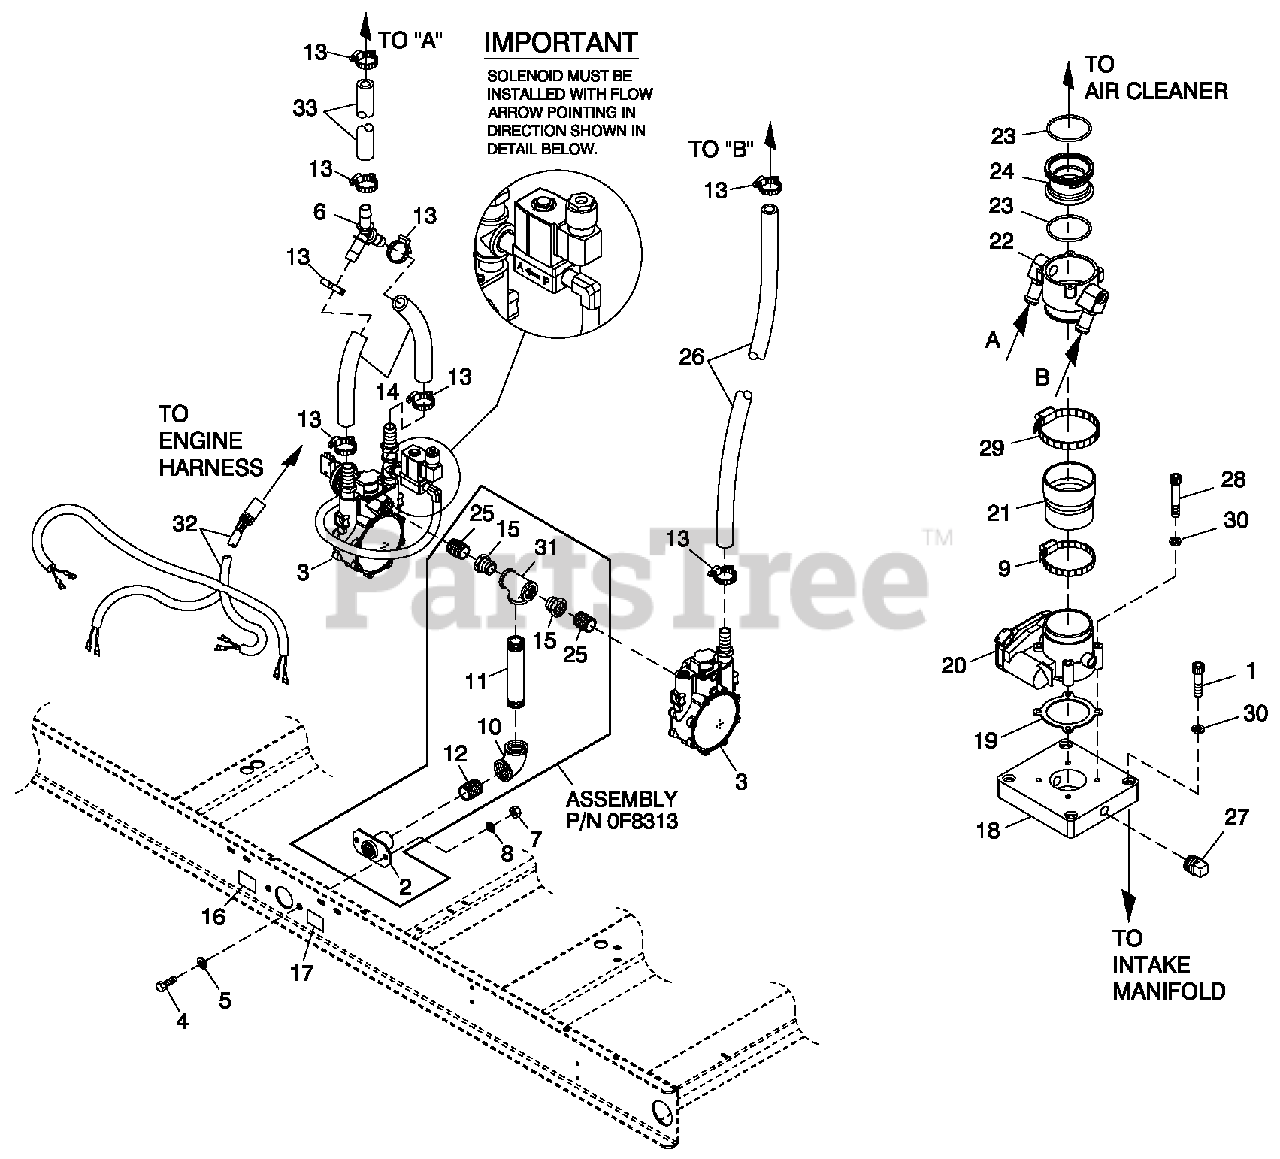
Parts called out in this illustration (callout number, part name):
1	SCREW SHC M6-1.0 X 25 G12.9 ZP
2	SUPPORT NAT GAS SOLENOID
3	REG ASSY 4.6L 80KW NG CPL
4	SCREW HHC M12-1.75 X 20 G8.8
5	WASHER FLAT 1/2 ZINC
6	Y CONNECTOR 500 SERIES BARBS
7	NUT HEX M12-1.75 G8 YEL CHR
8	WASHER LOCK 1/2
9	CLAMP HOSE #44 2.31-3.25
10	ELBOW 90D 1-1/4 NPT
11	NIPPLE PIPE 1-1/4 NPT X 3
12	NIPPLE CLOSE 1.25 NPT X 1.625
13	CLAMP HOSE #8 .53-1.00
14	HOSE 3/4 ID SAE-30R2 (14" LG)
15	BSHG RDCR HEX 1-1/4-3/4
16	DECAL INLET PRESSURE
17	DECAL FUEL INLET NG
18	ADAPTER INTAKE MACHINED 4.6 NG
19	GASKET GOVERNOR ACTUATOR
20	ACTUATOR BOSCH 60 GOVERNOR
21	REDUCER 3.0" TO 2.75" TURBO
22	MIXER 40/60MM ACTUATOR ASSY
23	O-RING 2-3/4 X 3/32 X 2-15/16
24	VENTURI THROTTLE 38MM
25	NIPPLE CLOSE 3/4 X 1.375
26	HOSE 3/4 ID SAE-30R2 (43" LG)
27	PLUG STD PIPE 1/4 STEEL SQ HD
28	SCREW SHC M6-1.0 X 50 G8.8
29	CLAMP HOSE #52 2.81-3.75
30	WASHER LOCK M6-1/4
31	PIPE TEE 1-1/4 NPT
32	HARNESS, FUEL JUMPER DUAL REG
33	HOSE 3/4 ID SAE-30R2 (27" LG)
